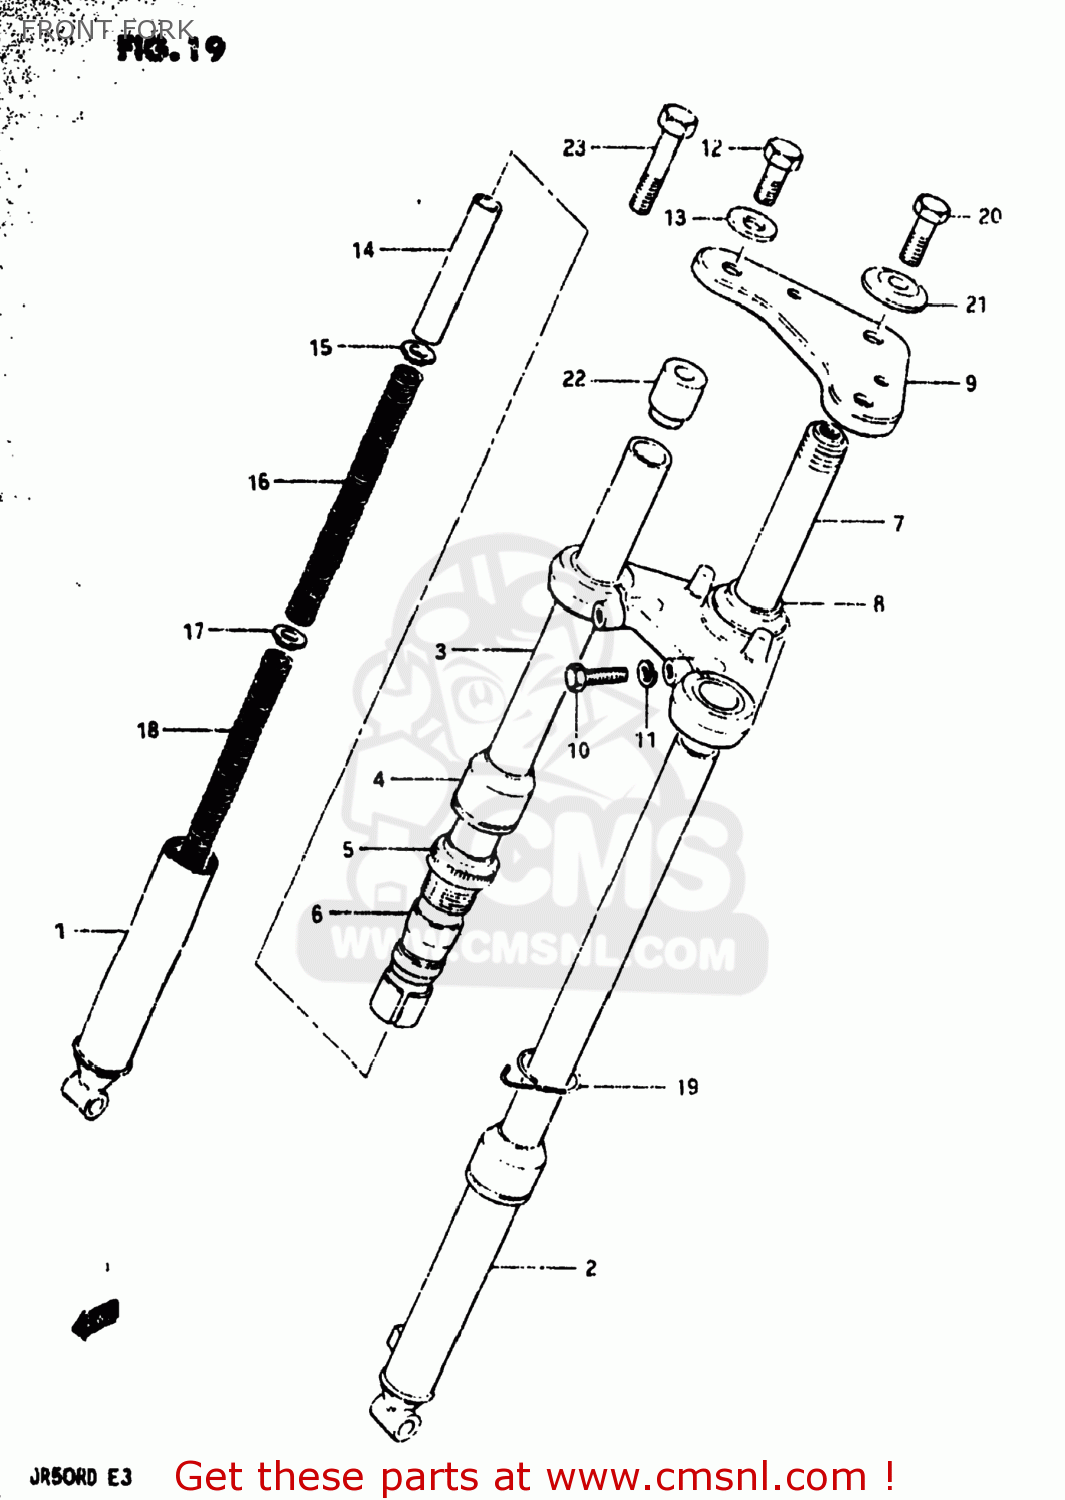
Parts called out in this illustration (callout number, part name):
1	TUBE,OUTER,RIGHT
2	TUBE,OUTER,LEFT
3	TUBE,INNER
4	SEAL,DUST
5	NUT,OUTER
6	STOPPER
7	STEM,STEERING
8	RACE,STEERING,OUTER,LOWER
9	HEAD,STEERING STEM
10	BOLT
11	LOCK WASHER
12	BOLT
13	WASHER,STEERING STEM HEAD
14	SPACER
15	GUIDE,SPRING
16	SPRING,NO.1
17	GUIDE,SPRING NO.2
18	SPRING,NO.2
19	CLIP
20	BOLT
21	WASHER(33.5X10.5X4.2)
22	SPACER,FR FORK INNER TUBE
23	BOLT,FRONT FORK INNER TUBE
